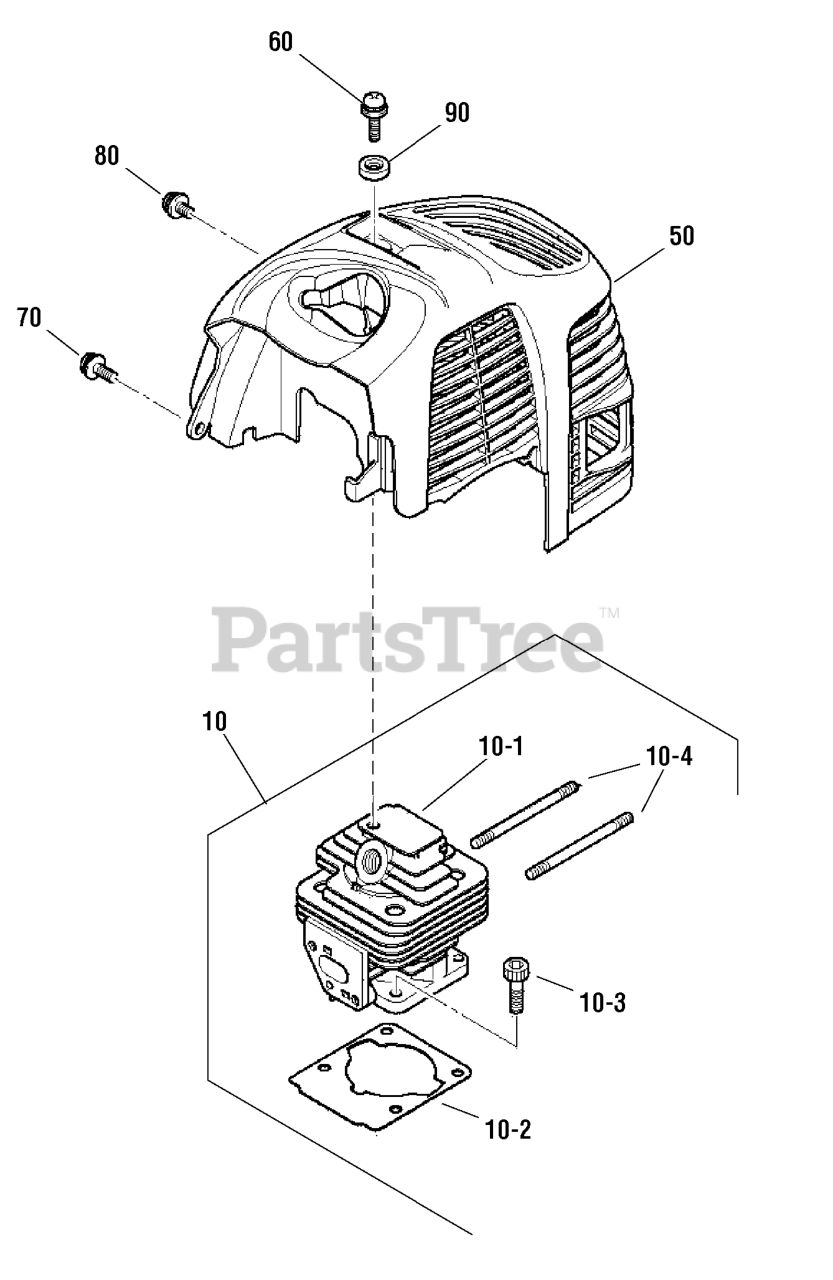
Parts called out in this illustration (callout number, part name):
10	CYLINDER ASSEMBLY
10-1	CYLINDER
10-2	GASKET, Cylinder
10-3	BOLT
10-4	BOLT, Stud
50	COVER, Top
60	SCREW & WASHER
70	SCREW & WASHER
80	SCREW & WASHER
90	WASHER
